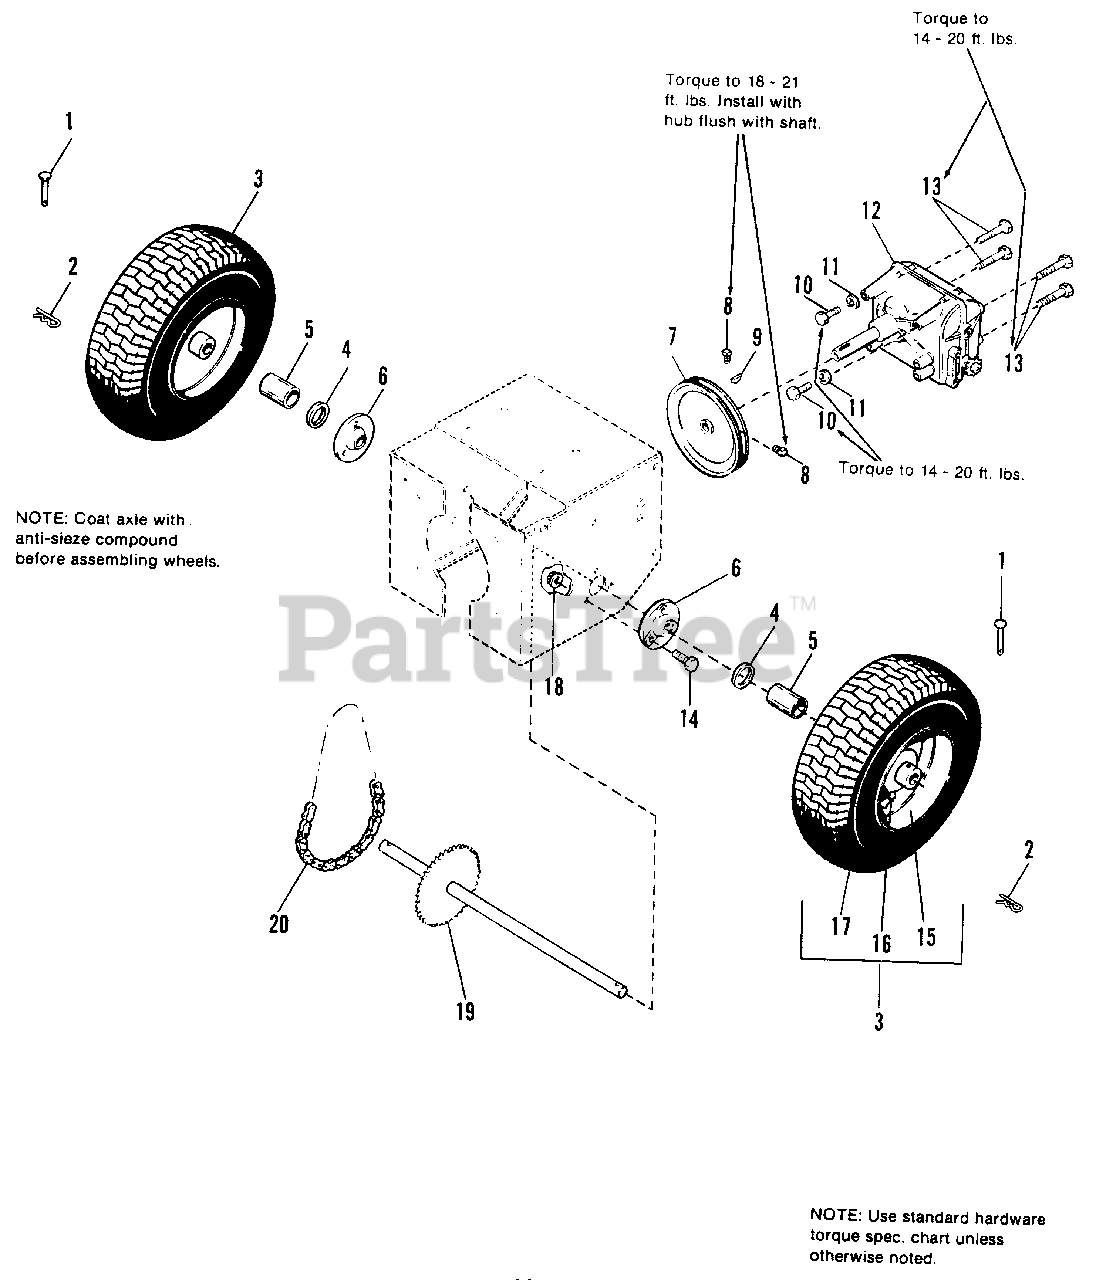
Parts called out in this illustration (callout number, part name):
1	PIN
2	CLIP, Hair Pin
3	TIRE & WHEEL ASSY.
4	WASHER
5	SPACER, Wheel
6	BEARING, Wheel
7	PULLEY ASSY., Traction
8	SETSCREW, Sq. Hd., 5/16-18 x 5/8
9	KEY, Woodruff, Hi Pro, 3/16 x 3/4
10	CAPSCREW, Hex, 5/16-18 x 3/4
11	LOCKWASHER
13	SCREW, Hex, Taptite, 5/16-18 x 5/8
14	SCREW, Hex Whizlock, 5/16-18 x 3/4
16	VALVE STEM & CAP
17	TIRE, 4.10/3.5-6 Turf
18	NUT, Hex, Fl. Hd. Lock, 5/16-18
20	DRIVE CHAIN
